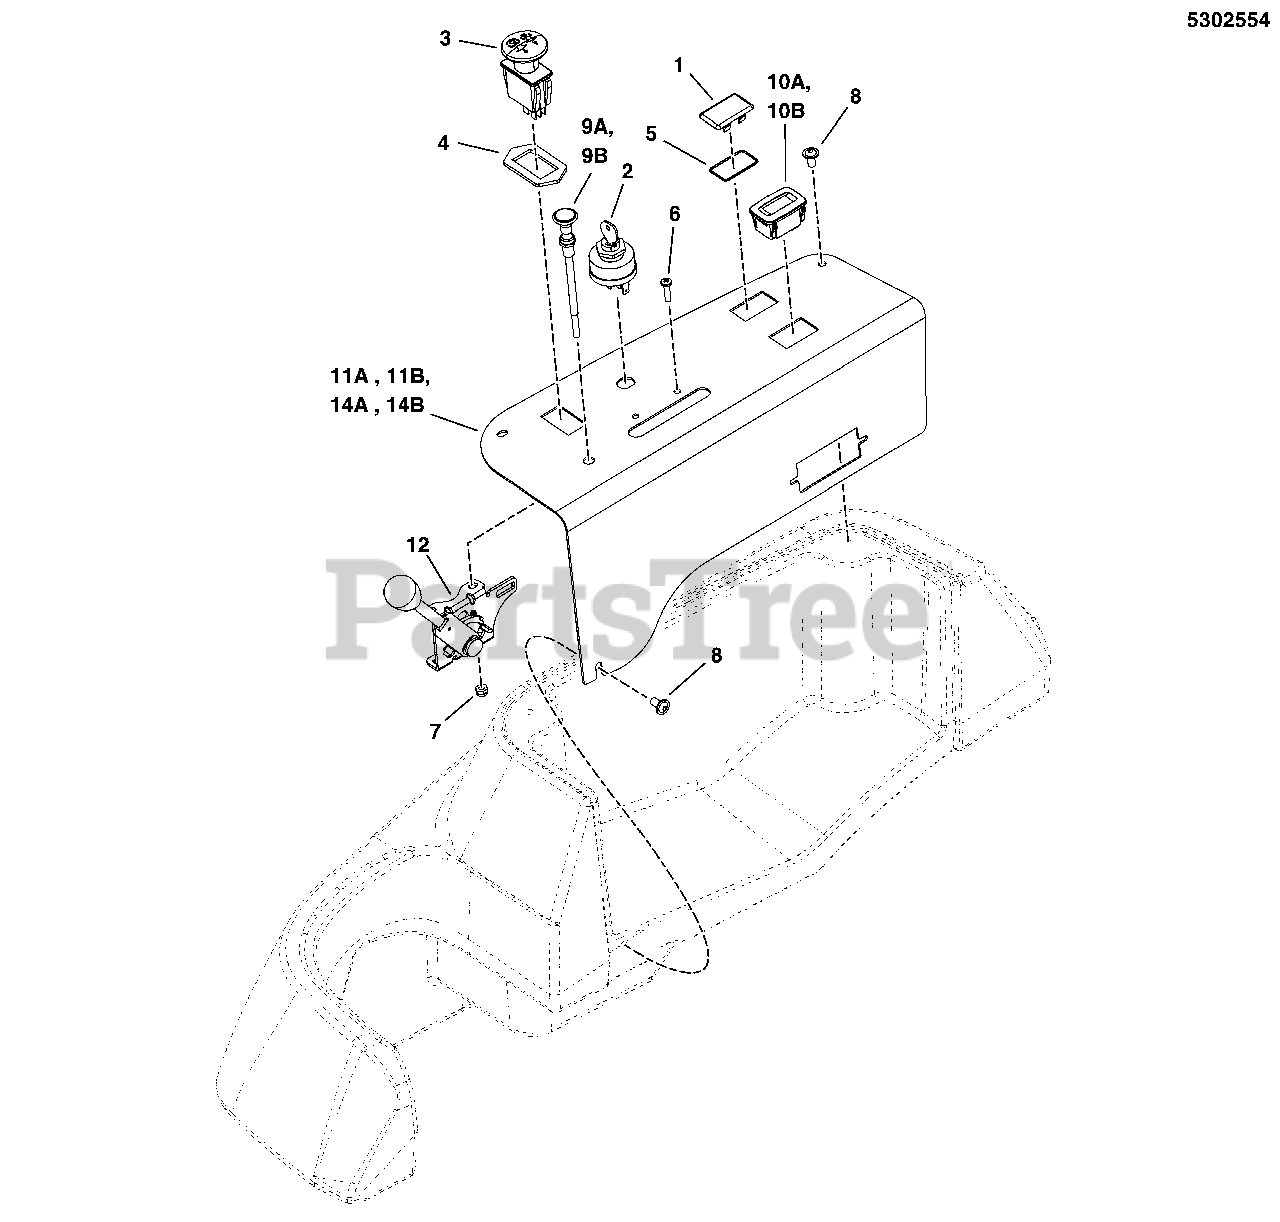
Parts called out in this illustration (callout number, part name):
1	PLUG, .820X1.44 HOLE, BLACK PLASTIC
2	SWITCH ASSEMBLY, Ignition Indak No Keys/Hdwr
3	SWITCH, BLADE ENGAGEMENT
4	RING, SWITCH RETAINER
5	O-RING, 7/8" ID X 1/16" W
6	SCREW, #10-24 X 3/4" ROUND PHILLIPS
7	NUT, Nylock, #10-24, GR2
8	SCREW, ALLEN HEAD 1/4-20X.500 ZINC PHOS
9A	CABLE, CHOKE CONTROL, 43.5"
9B	CABLE, Choke Control, 47"
10A	HOUR METER, ASSEMBLE
10B	HOUR METER
11A	PLATE, CONTROL PANEL - BLACK
11B	PLATE, CONTROL PANEL, IS600Z - BLK
12	LEVER, THROTTLE CONTROL
14A	PLATE, CONTROL PANEL, IS600Z - BLK
14B	PANEL, CONTROL, IS2100Z - BLK
